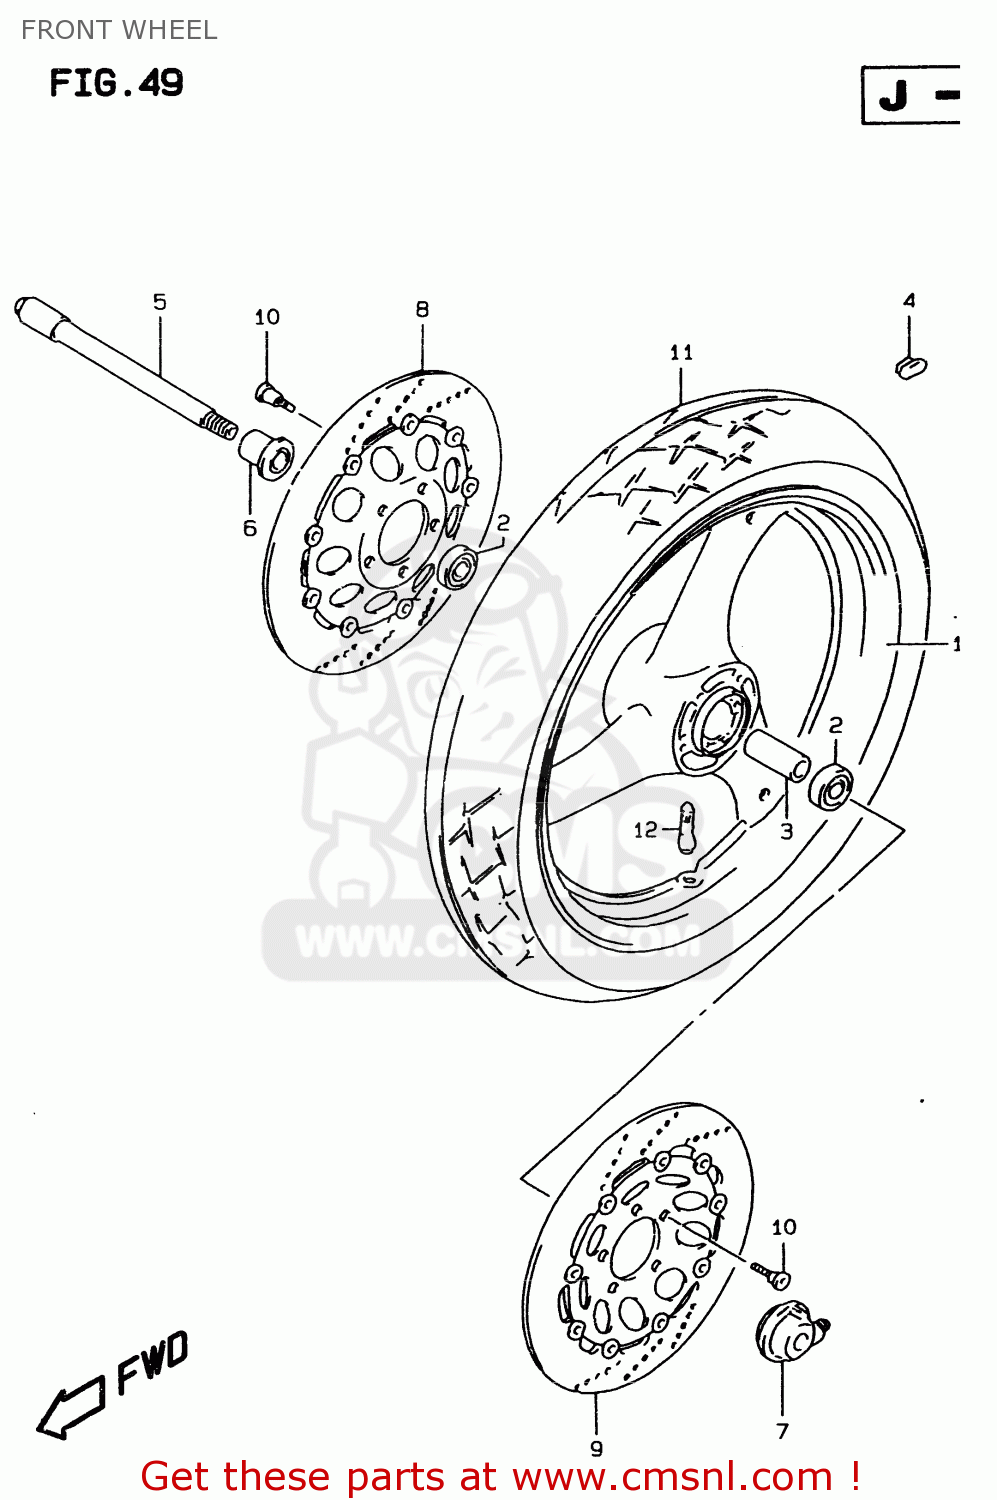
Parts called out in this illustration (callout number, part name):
1	WHEEL,FRONT (17XMT3.00)(
2	BEARING
3	SPACER(17.5X22.5X73)
4	BALANCER,WHEEL (10G)
5	AXLE,FR
6	SPACER,FR AXLE,R
7	BOX ASSY,SPEEDOMETER GEAR
8	DISC,FR BRAKE,R
9	DISC,FR BRAKE,L
10	BOLT 8X33
11	TIRE,FRONT 110/70-17.5
12	VALVE ASSEMBLY,WHEEL,TR412
